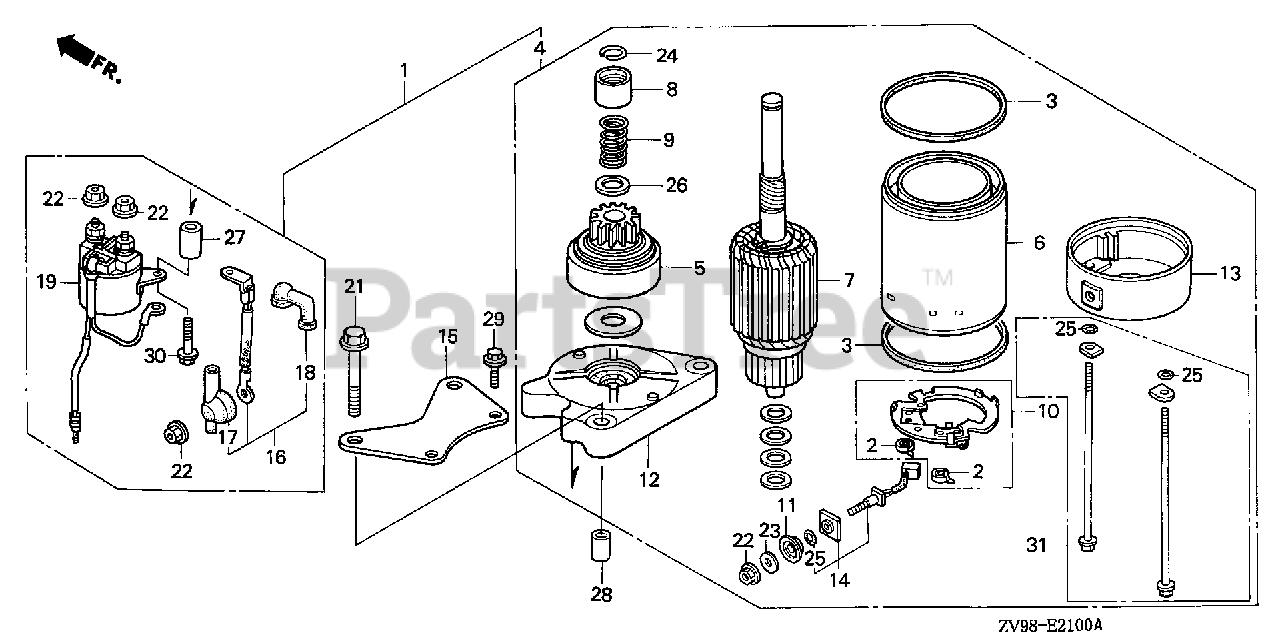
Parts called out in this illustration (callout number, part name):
1	STARTER MOTOR ASSY.
2	SPRING, CARBON BRUSH
4	STARTER MOTOR UNIT
8	PIECE, STOPPER
9	SPRING, RETURN
10	HOLDER, BRUSH
12	BRACKET, FR.
13	BRACKET, RR.
14	TERMINAL UNIT
15	STAY, STARTER MOTOR
16	WIRE, MAGNETIC SWITCH
17	COVER, STARTER TERMINAL
18	COVER, MAGNETIC SWITCH TERMINAL
19	SWITCH ASSY., STARTER MAGNETIC
21	BOLT, FLANGE (8X45)
22	NUT-WASHER (6MM)
23	WASHER (6MM)
24	CIRCLIP (14MM)
25	O-RING (4X2)
27	COLLAR, DISTANCE
28	PIN, DOWEL (10X16)
29	BOLT, FLANGE (6X16)
30	BOLT, FLANGE (6X25)
30	BOLT, FLANGE (6X25) (SH)
31	BOLT SET, SETTING
